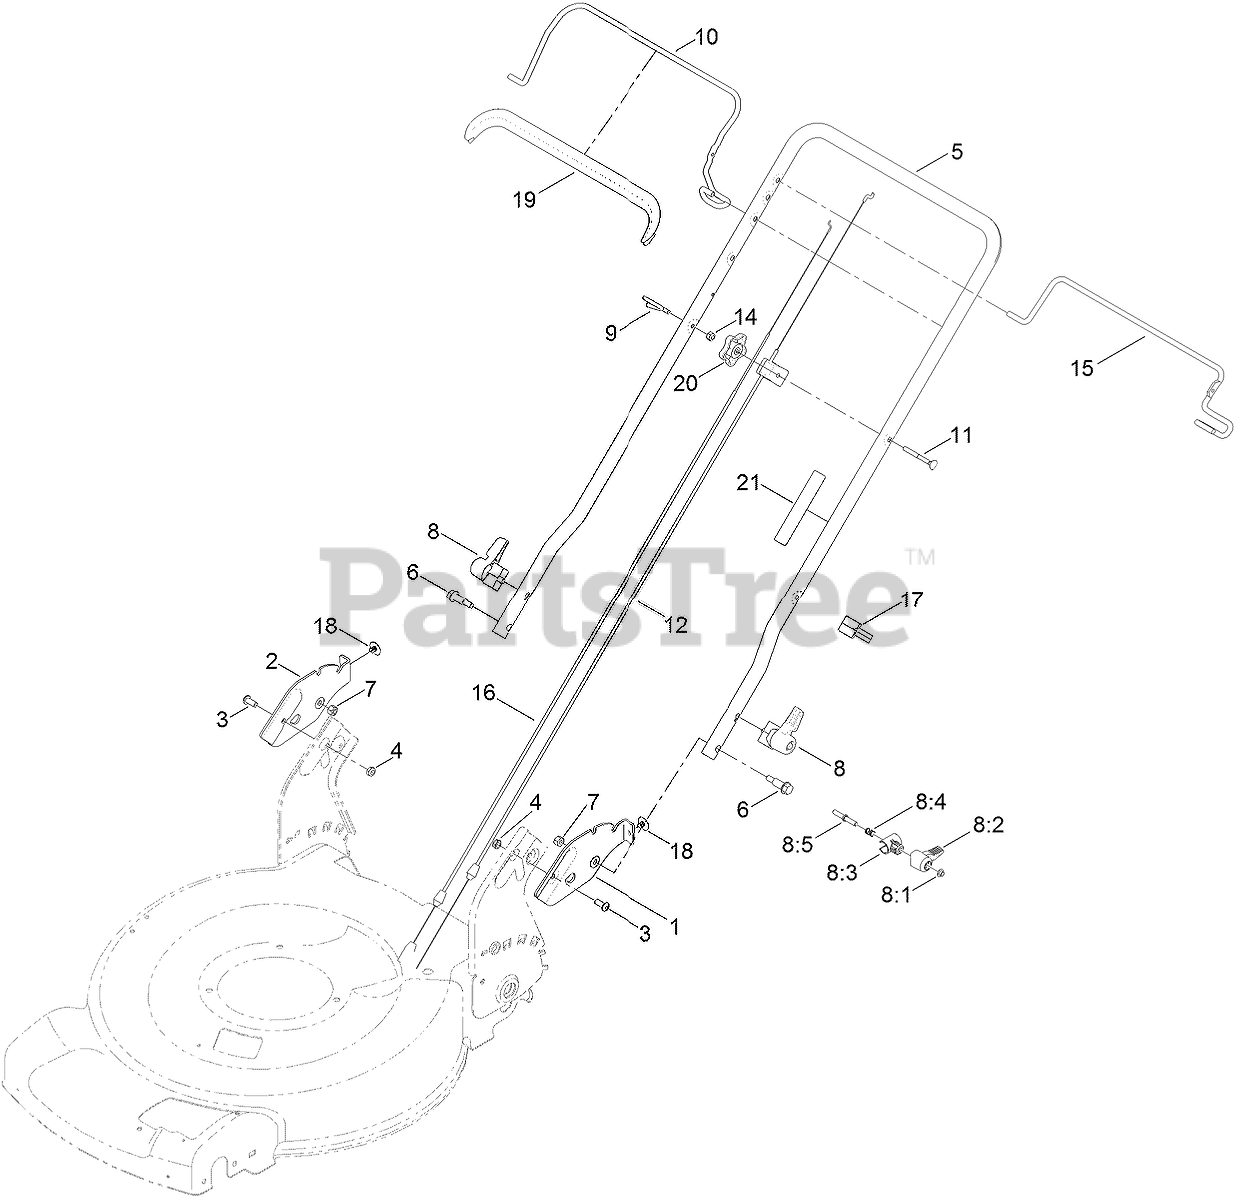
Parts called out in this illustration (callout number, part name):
1	PLATE-HANDLE, LH
2	PLATE-HANDLE, RH
3	SCREW-HSBH
4	NUT-LOCK, NI
6	BOLT-SHOULDER
7	NUT-LOCK, NI
8	QUICK RELEASE ASM
8:1	NUT-PUSH
8:2	LEVER
8:3	ANCHOR-SPRING
8:4	SPRING-COMPRESSION
8:5	ROD-RELEASE
9	GUIDE-ROPE
10	BAIL-BRAKE
11	SCREW-HANDLE
12	CABLE-BRAKE
14	NUT-LOCK, NI
15	BAIL-TRACTION
16	CABLE-TRACTION
17	GUIDE-CABLE
18	CLIP-TREE
19	COVER-BAIL
20	KNOB-HANDLE, LOCKING
21	DECAL-TRACTION, ADJUST
